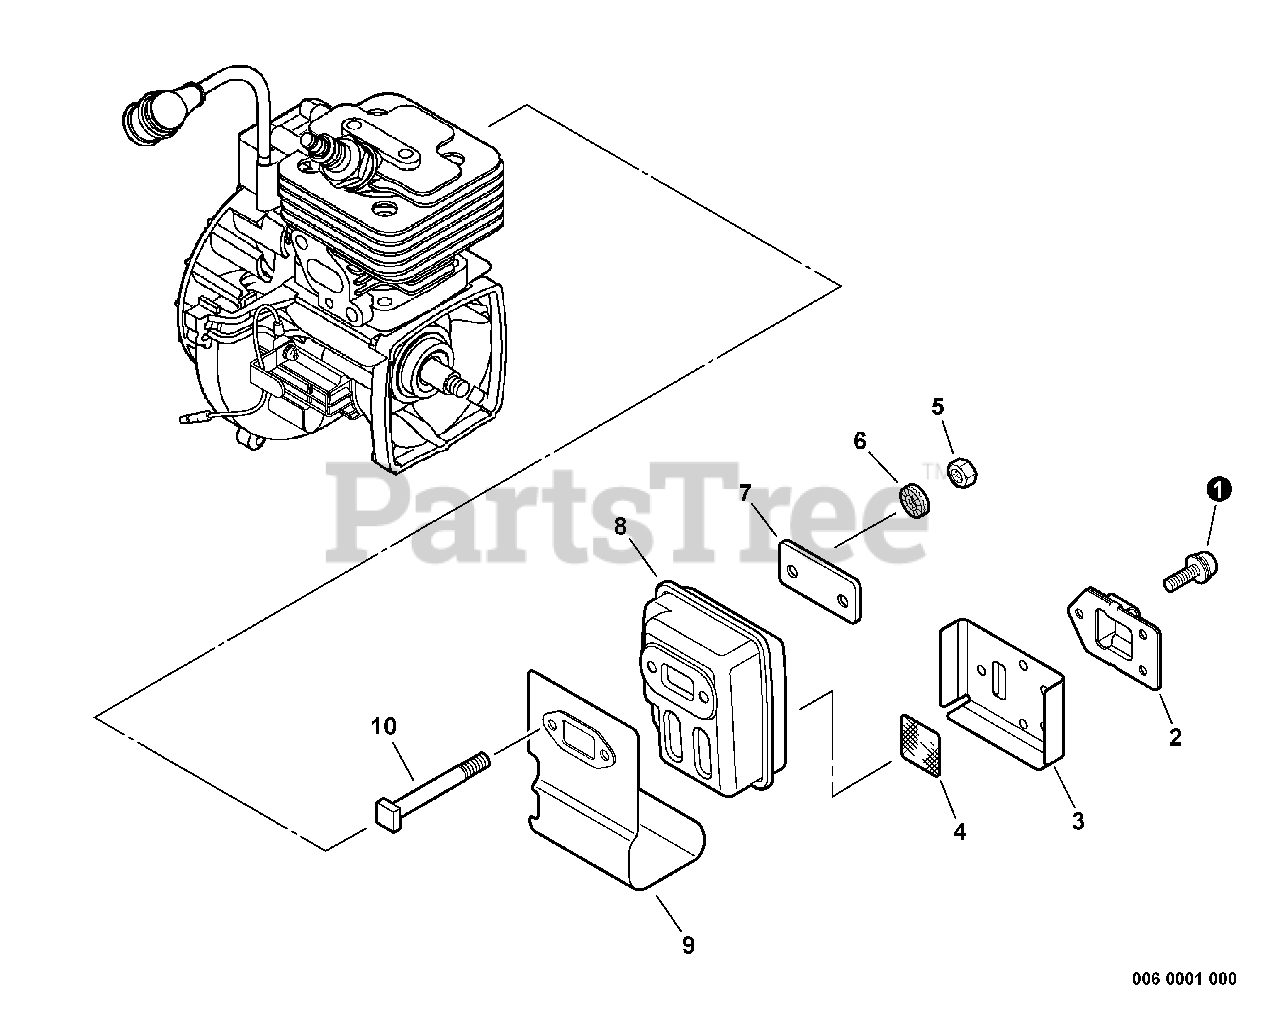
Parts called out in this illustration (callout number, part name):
1	SCREW 4×12
2	GUIDE, EXHAUST
3	GASKET, EXHAUST
4	SCREEN, SPARK ARRESTER
5	NUT M5
7	PLATE, EYE
8	MUFFLER
9	HEAT SHIELD, EXHAUST
10	BOLT 5×60
